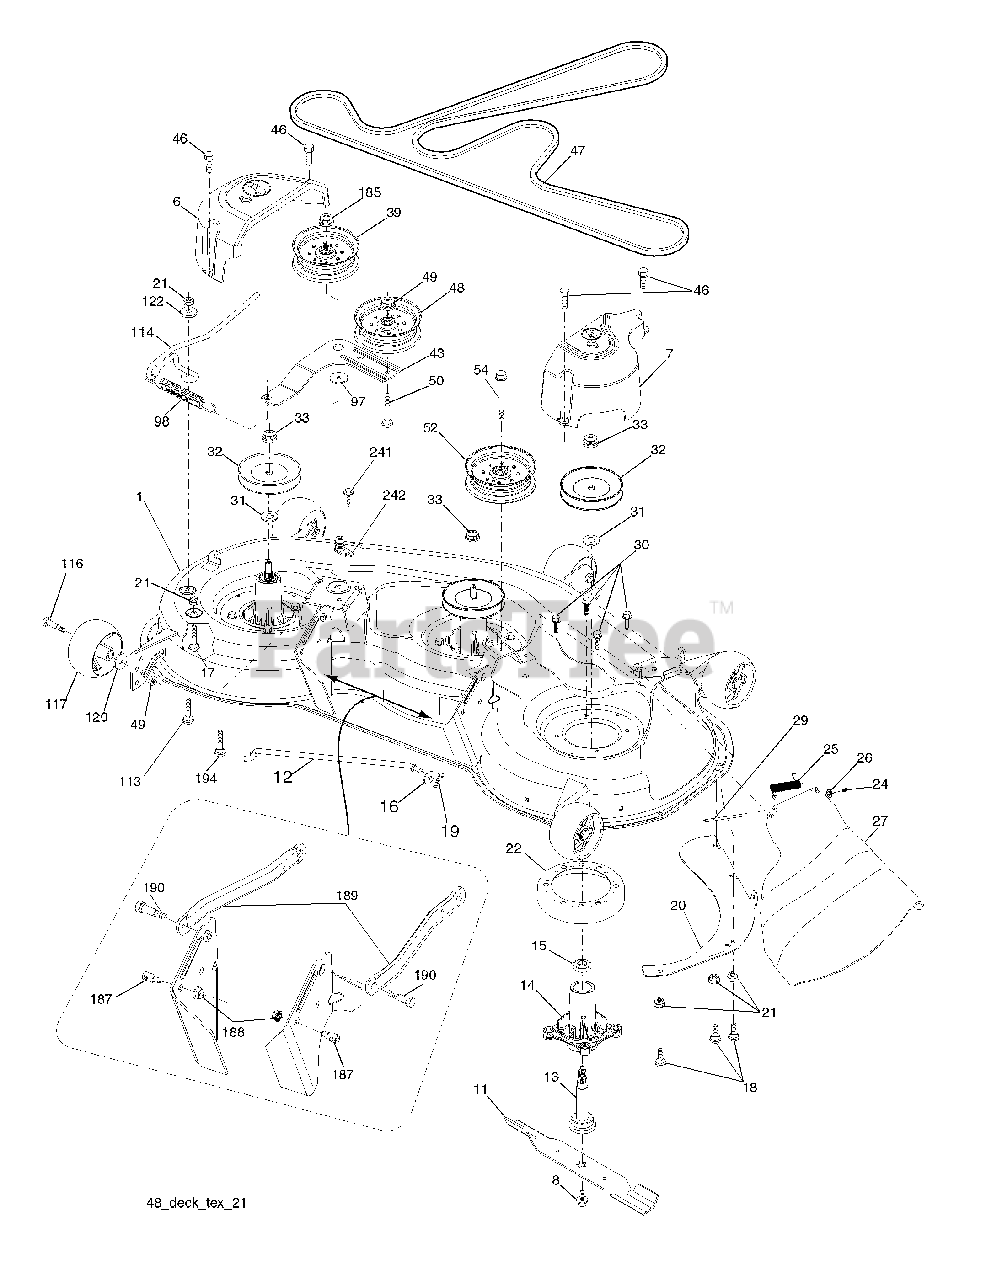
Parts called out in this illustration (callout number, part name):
1	Deck Weldment Mower
6	Cover Mandrel LH
7	Cover Mandrel RH
8	Bolt 7/16 Asm. Blade
11	Blade High Lift
12	Rod Anti-Sway
13	Shaft Asm. w/Lower Bearing
14	Housing, Mandrel
15	Bearing, Ball, Mandrel
16	Washer 13/23 x 13/16 x 1 2Ga.
17	Bolt Carr. 5/16-18 x 5/8
18	Bolt RdHd 5/16-18 unc x 5/8
19	Pin Cotter 5/16 Bowtie Lock
20	Baffle Vortex
21	Nut, Crownlock 5/16-18 unc
22	Stripper Mandrel Deck
24	Cap Sleeve
25	Spring, Torsion
27	Deflector Shield
29	Rod, Hinge
30	Screw, Thdroll Washer Head
31	Washer, Spacer Mower Vented
32	Pulley, Mandrel
33	Nut, Flg. Top Lock
39	Pulley, Idler, Stationary
43	Arm, Idler
46	Screw, Thdroll. 1/4-20 x 5/8
47	Belt Drive Deck
48	Pulley Idler Primary
49	Nut, Lock Flg. 3/8-16 unc
50	Screw 3/8-16 x 1-1/4 unc
52	Pulley Idler
54	Bolt Carriage 3/8-16 x 1-1/2 Gr.5
97	Washer Hardened
98	Spring Drive
113	Bolt Rdhd Sqnk 5/16-18 x 3/4
114	Rod Tension Relief
116	Bolt, Shoulder
117	Gauge Wheel
120	Washer 13/32 x 1-1/4 x 12 Ga.
122	Bushing Tension Relief
185	Nut Lock Flange 7/16-14 Gr. 5
187	Stud Fastener w/"D" Anti-Rotation
188	Nut Lock Hex Flange
189	Arm Susp. Mower Rear
190	Bolt Shoulder
194	Bolt Carr Sqnk 3/8-16 x 2-1/4
242	Washout Port
242	Mandrel Assembly
242	Coupling, Quick Connect
242	Replacement Mower, Complete
